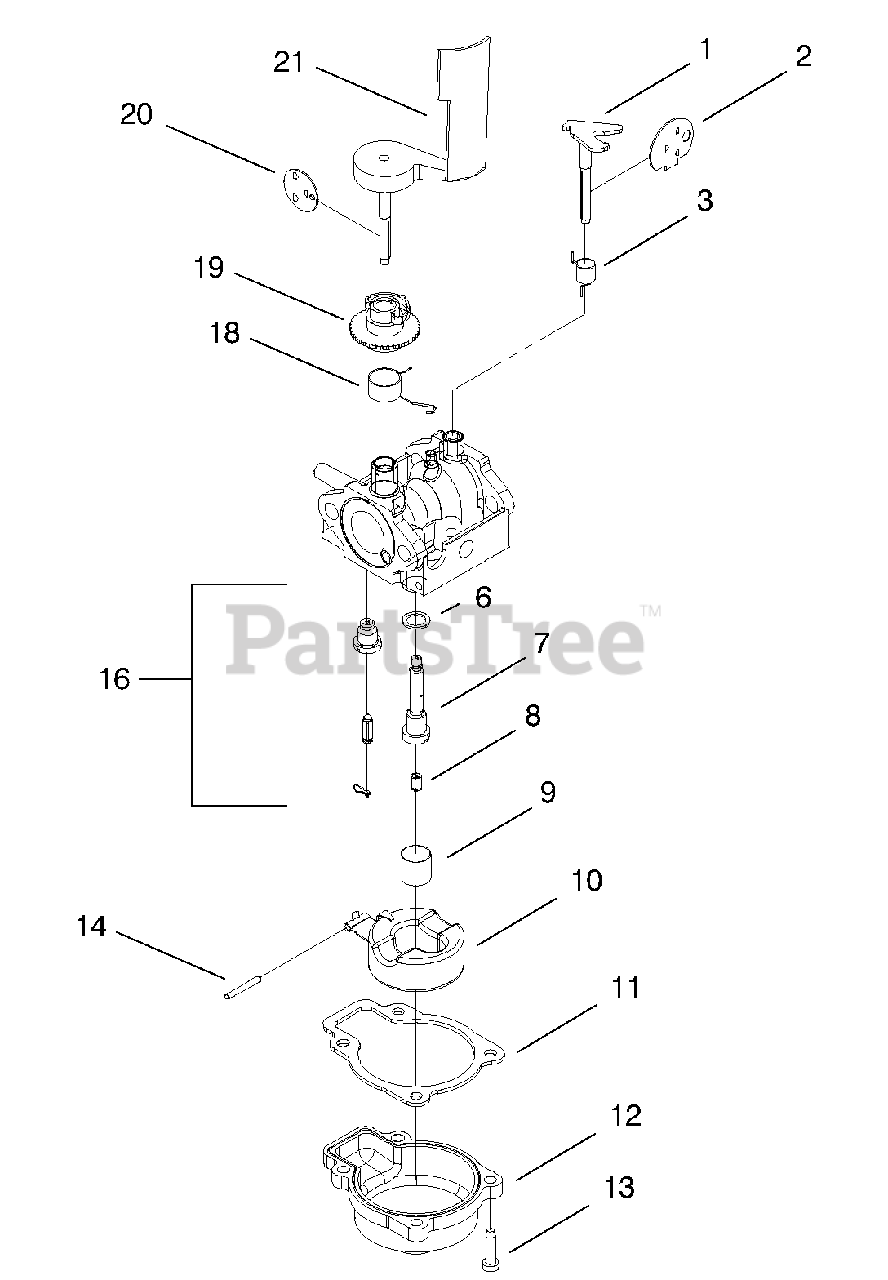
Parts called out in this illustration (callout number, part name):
1	SHAFT-CHOKE
2	DISC-CHOKE
3	SPRING-CHOKE
8	JET-MAIN (77.5)
9	FILTER-FUEL
10	FLOAT & ARM ASM
12	CHAMBER-FLOAT
13	SCREW-HH
14	PIN-STRAIGHT
16	VALVE/SEAT-FLOAT
18	SPRING-THROTTLE
19	COLLAR-ADJUST, AIRVANE
20	DISC-THROTTLE
21	Air Vane&shaft
